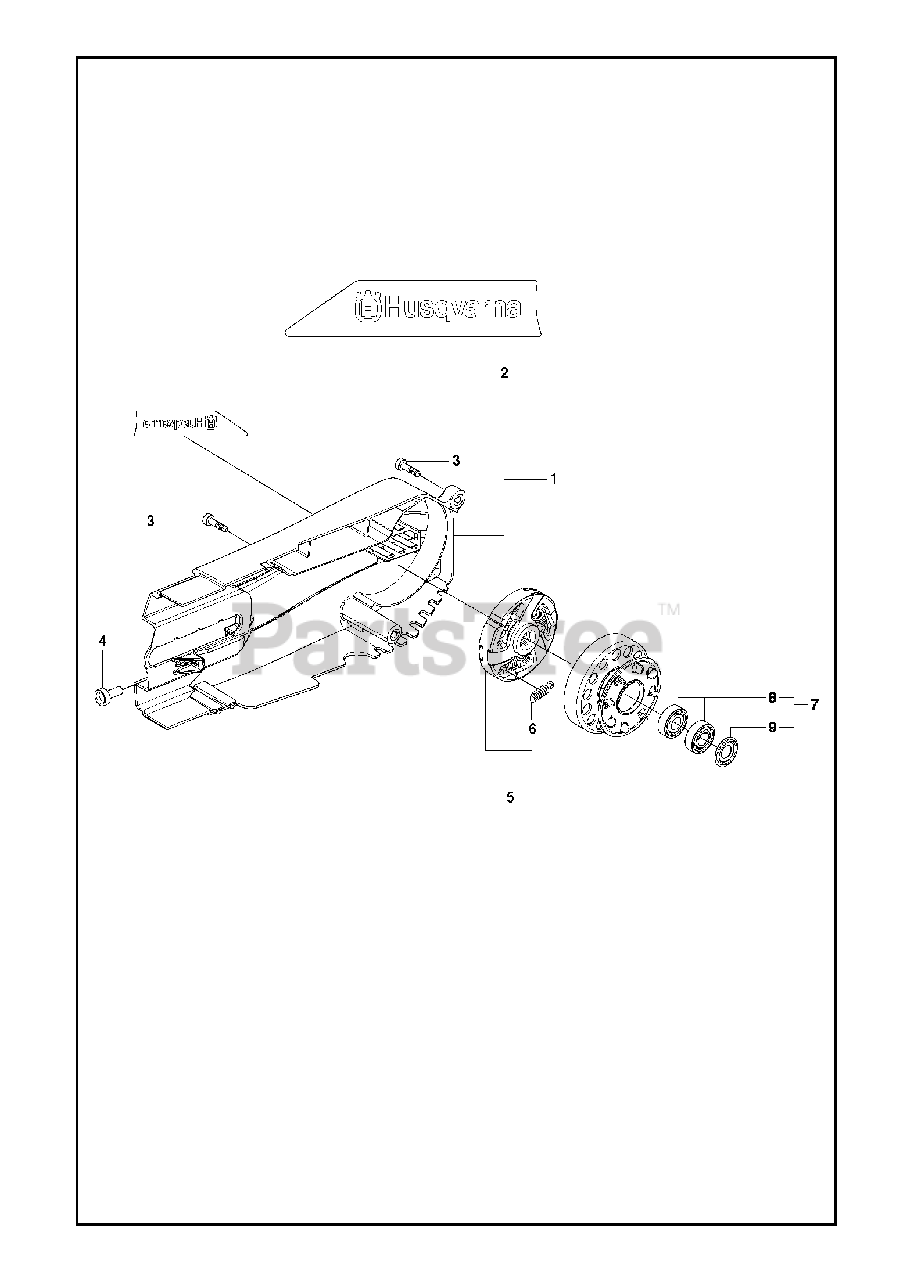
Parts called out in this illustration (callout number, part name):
1	BELT GUARD ASSY
3	SCREW ITXSCM
5	CLUTCH ASSY
6	CLUTCH SPRING
7	DRIVING PULLEY ASSY"14"""
7	DRIVING PULLEY ASSY"16"""
8	BALL BEARING
